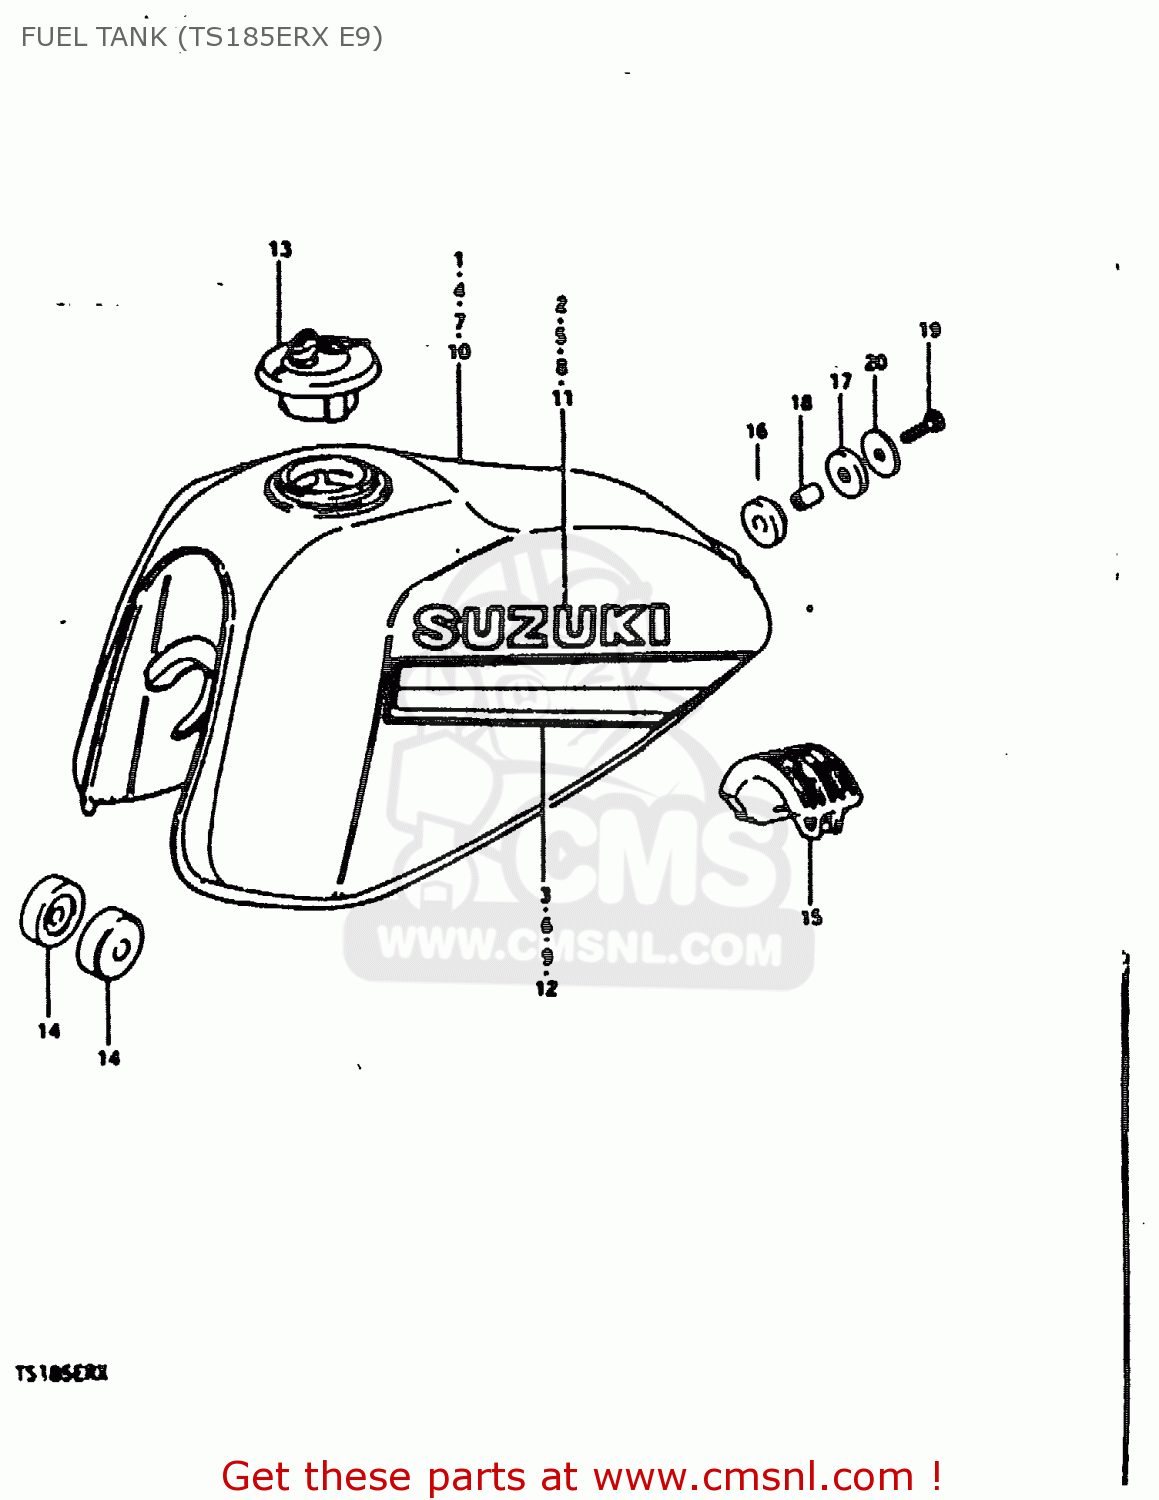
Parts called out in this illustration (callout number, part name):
1	TANK, FUEL (BLACK)
2	EMBLEM
3	TAPE SET
4	TANK, FUEL (YELLOW)
5	EMBLEM(BLACK)
6	TAPE SET
7	TANK, FUEL (RED)
8	EMBLEM
9	TAPE SET
10	TANK, FUEL (WHITE)
11	EMBLEM(BLACK)
12	TAPE SET
13	CAP SET,FUEL TANK
14	CUSHION
15	CUSHION,FUEL TANK
16	CUSHION
17	CUSHION
18	SPACER(8.5X12X19)
19	BOLT (8X30)
20	WASHER (8.5X29X1.6)
